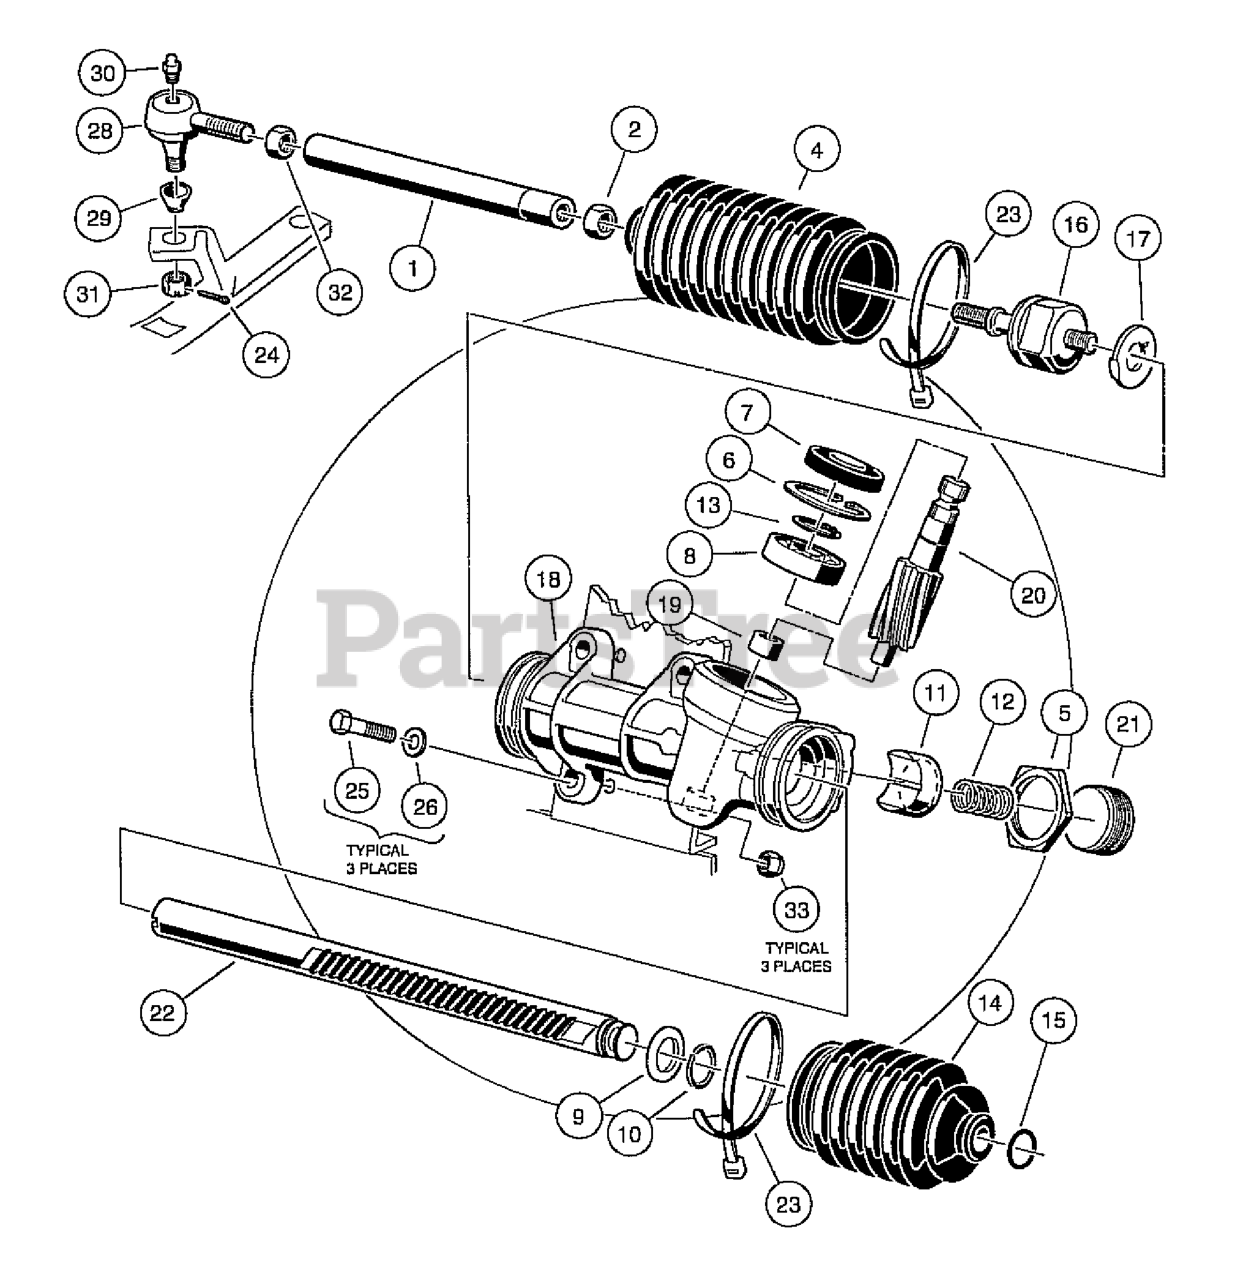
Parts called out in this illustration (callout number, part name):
1	DRAG LINK RACK & PINION
2	12MM HEX NUT
3	ASM, STEERING RACK, 3.13
4	BELLOWS, LONG
5	Rack Screw Locknut
7	SEAL, STEERING PINION DUST
8	BEARING BALL
9	STOP WASHER
10	STOP RING C - TYPE
11	SUPPORT YOKE
12	RACK GUIDE PRESSURE SPRING
13	C-TYPE STOP RING
14	BELLOWS, SHORT
15	DUST SEAL RETAINING RING
16	INNER BALL JOINT ASM
17	WASHER, TAB
18	Box, Steering Gear
19	Bearing, Lower Pinion
20	Pinion, Steering
21	Screw, Rack Guide
22	Rack, Steering
23	TIE WRAP, 8" NYLON
24	PIN,CUT COTTER
25	SCREW, 3/8-16 X 1.5 HX HD CAP
26	WASHER, 3/8 FLAT
27	BALL JOINT, LH
28	BALL JOINT, LH
29	SEAL, VERTICAL SOCKET DUST
30	FITTING, 1/4-28 THRD FRM GREAS
31	NUT, 3/8-24 UNF HEX THICK SLOT
32	NUT, 1/2-20 HEX
33	LOCKNUT, 3/8-16 HEX
